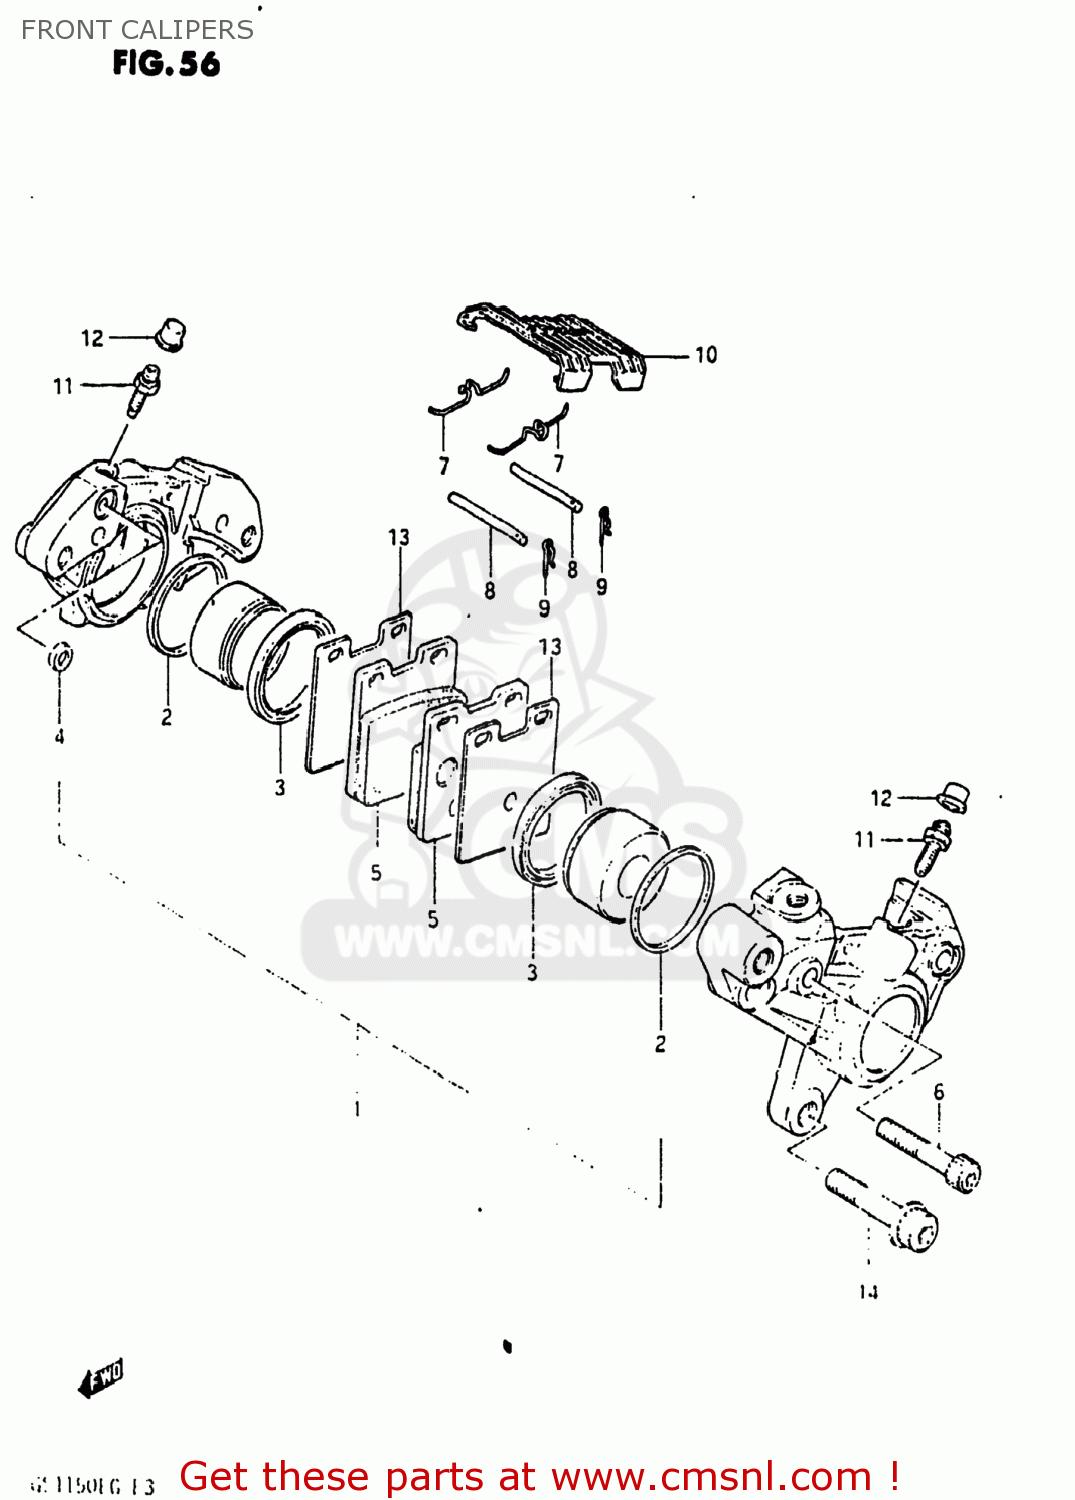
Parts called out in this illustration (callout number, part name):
0	CALIPER ASSEMBLY,RIGHT
1	PISTON SET
2	SEAL,PISTON
3	BOOT,PISTON
4	SEAL,JOINT
5	PAD,BRAKE
6	BOLT,CALIPER
7	SPRING
8	PIN,PAD
9	CLIP,PAD PIN
10	COVER,CALIPER
11	BLEEDER
12	CAP,BREATHER
13	SHIM,PAD
14	BOLT
